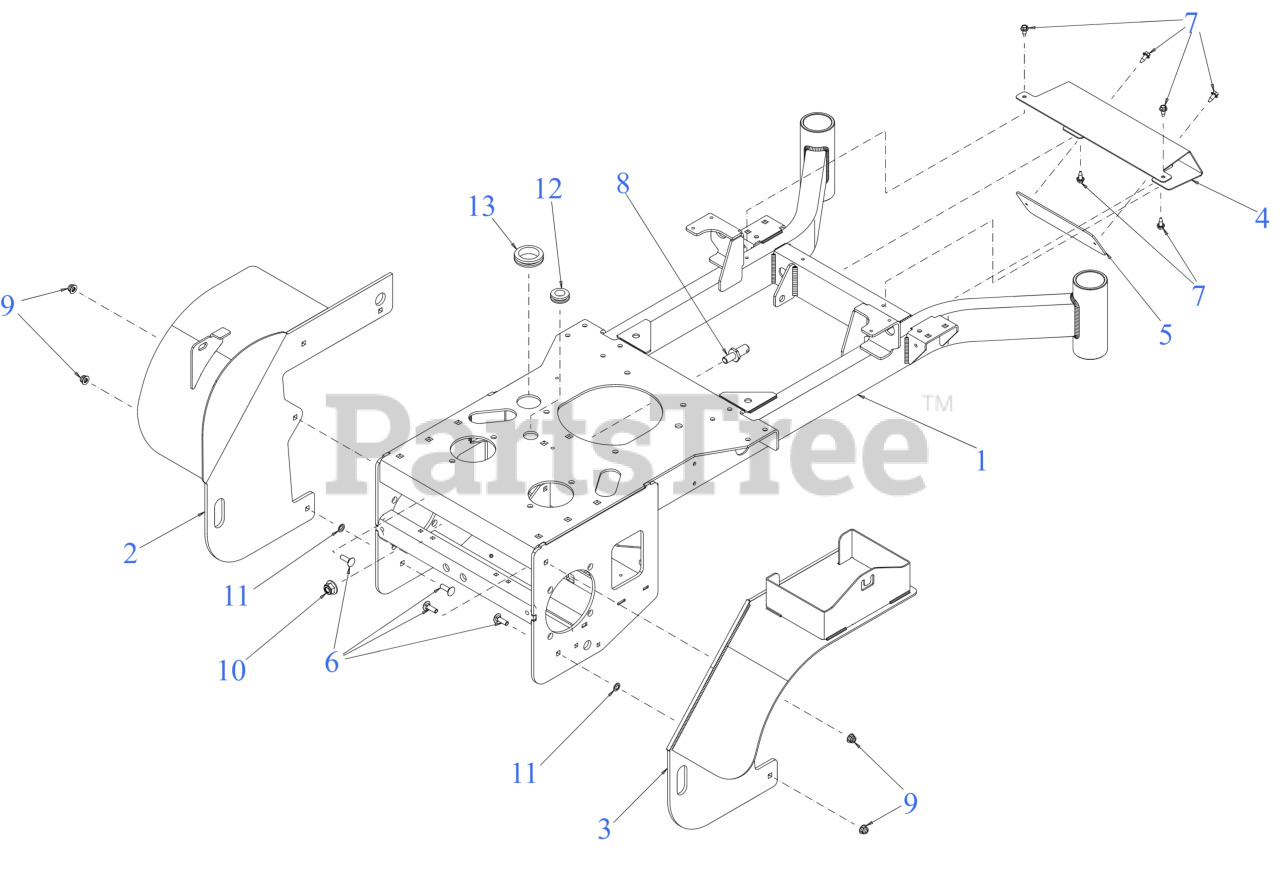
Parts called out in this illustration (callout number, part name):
1	FRAME
2	FENDER (LH)
3	FENDER (RH)
4	LOGO BRACKET (FRONT)
5	BACK PLATE
6	CARRIAGE BOLT 5/16-18 x 1.00
7	SCREW 1/4-20X.625
9	FLANGE LOCK NUT 5/16-18
12	RUBBER GROMMET
13	RUBBER GROMMET (1.50X2.13X.563)
